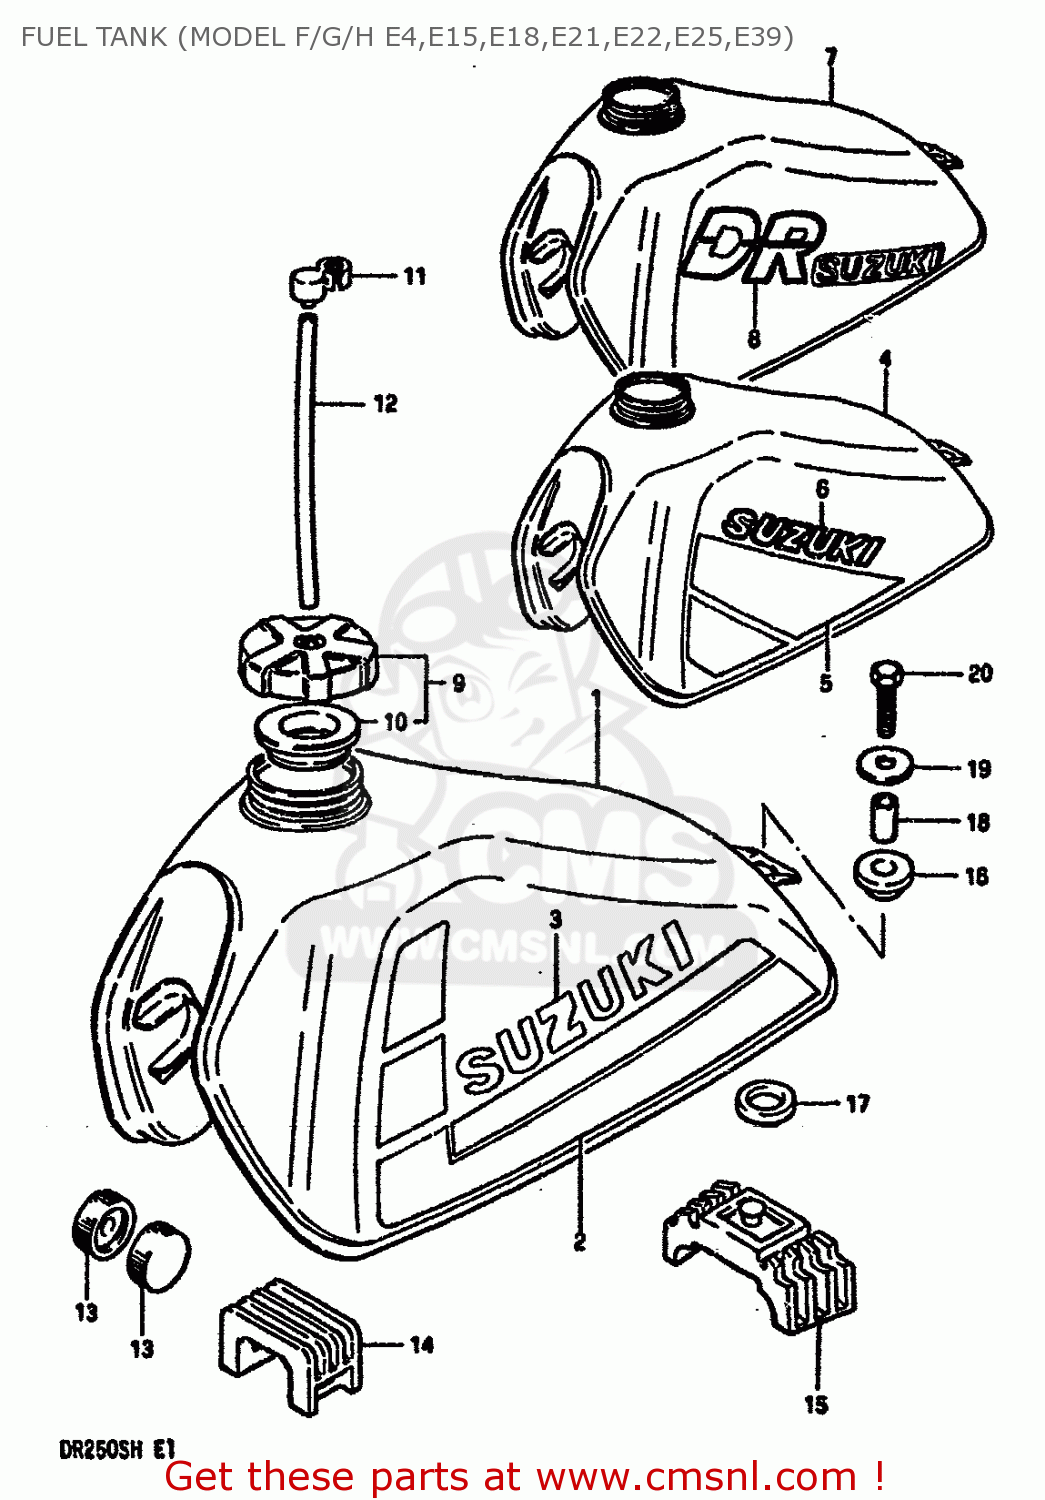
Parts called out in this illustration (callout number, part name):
1	TANK ASSY,FUEL (RED)
2	TAPE SET,FUEL TANK
3	EMBLEM
4	TANK ASSY,FUEL (RED)
5	TAPE SET,FUEL TANK
6	EMBLEM,FUEL TANK
7	TANK ASSY,FUEL (BLUE)
8	TAPE SET,FUEL TANK
9	CAP SET,FUEL TANK
10	GASKET (NAS)
11	CLAMP,FUEL TANK BREATHER HOSE
12	HOSE
13	CUSHION
14	CUSHION,TANK UPR FR
15	CUSHION,FUEL TANK,REAR
16	CUSHION
17	CUSHION
18	SPACER(8.5X12X19)
19	WASHER (8.5X29X1.6)
20	BOLT
